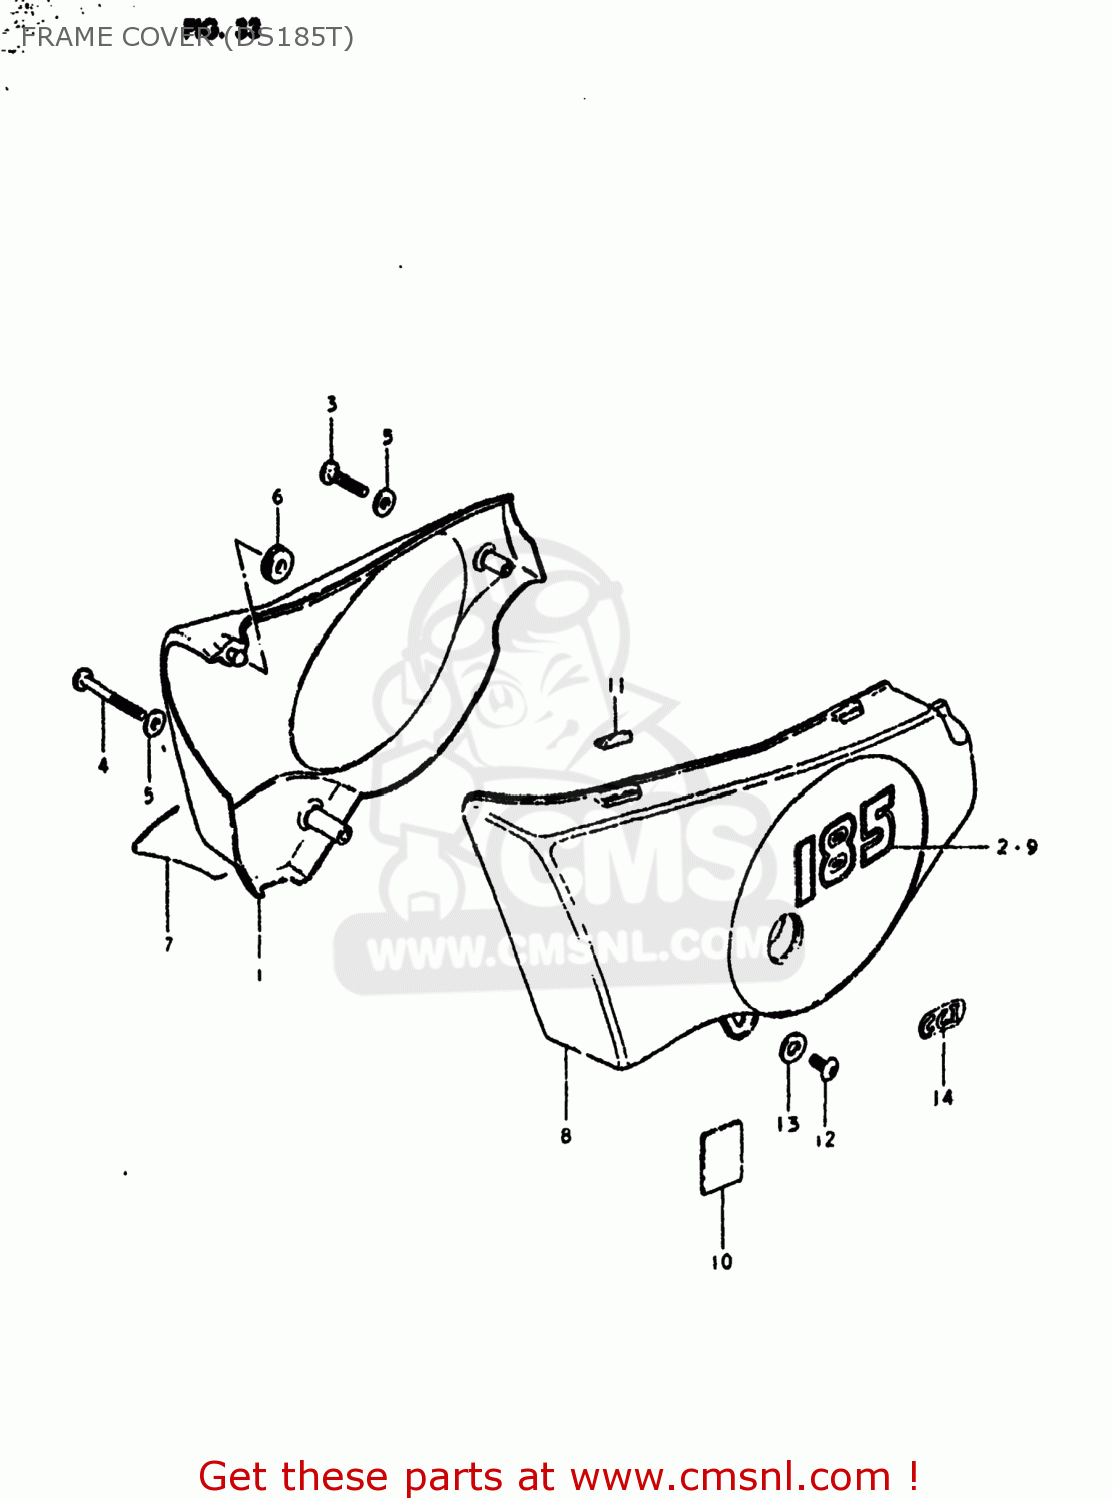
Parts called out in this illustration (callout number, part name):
1	COVER,FRAME,RIGHT
2	EMBLEM
3	SCREW
4	SCREW
5	WASHER
6	CUSHION
7	EMBLEM,FRAME COVER,RIGHT
8	COVER,FRAME,LEFT
9	EMBLEM,FRAME COVER
10	PROTECTOR(170X95X3.0)
11	CUSHION,FRAME COVER
12	SCREW 6X12
13	WASHER
14	EMBLEM,CCIS
